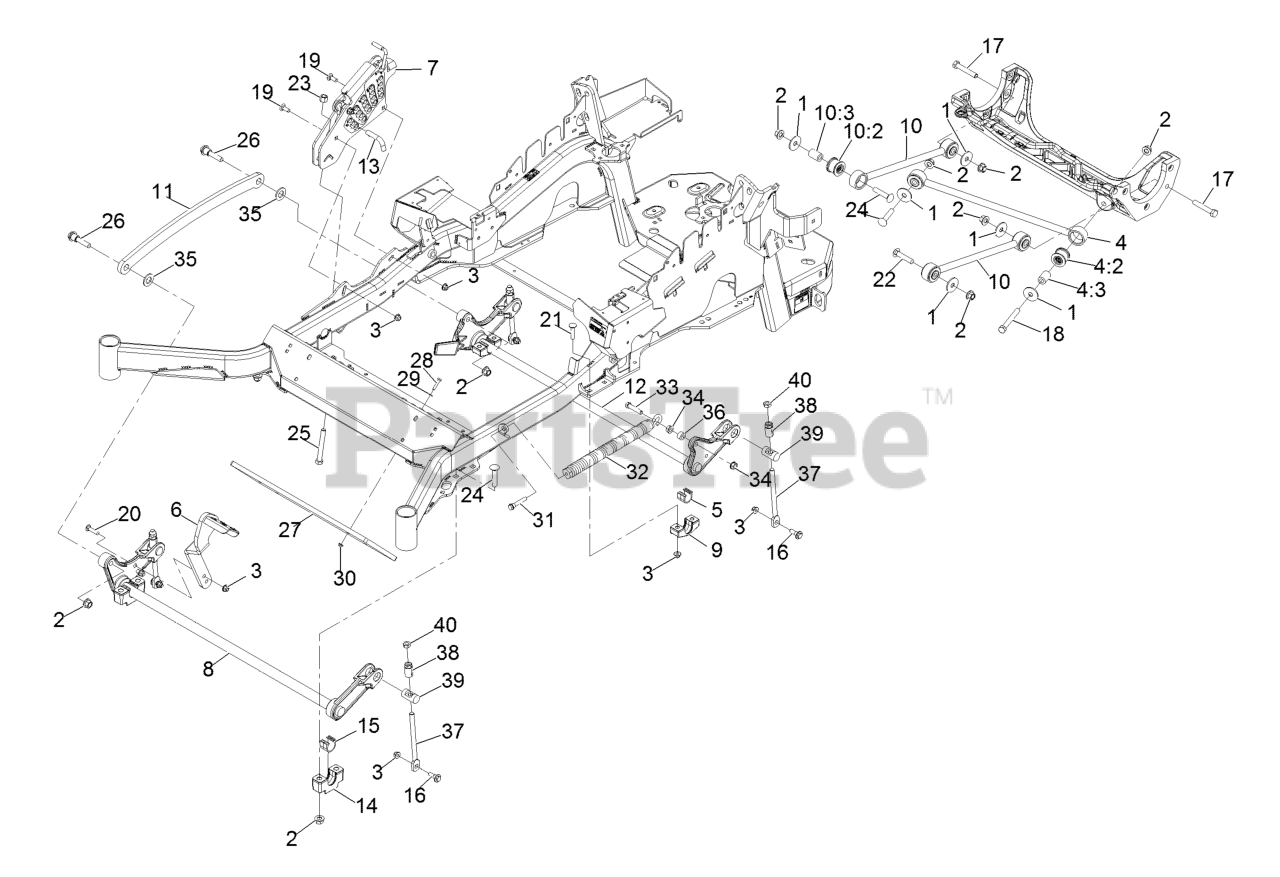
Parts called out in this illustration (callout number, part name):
1	WASHER-THRUST
2	Nut-Lock 1/2-13
3	NUT-HF, NI
4	PANHARD ROD ASM
4:2	BUSHING-SUSPENSION, RUBBER
5	BEARING-CROSS SHAFT, REAR
6	LEVER-FOOT
7	HOC ASM
8	DECKLIFT-FRONT
10	DECK STRUT ASM
10:2	BUSHING-SUSPENSION, RUBBER
11	LINK-LIFT, DECK
12	LIFT-DECK, REAR
13	PIN-HOC
14	SUPPORT-CROSS SHAFT, BEARING
15	BEARING-CROSS SHAFT, FRON
16	SCREW-SHOULDER, HHF
17	SCREW-HH
18	SCREW-HH
19	BOLT-CARR
20	SCREW-CARR
21	SCREW-CARR
22	SCREW-CARR
23	NUT-LOCK, NI
24	Bolt-Carriage 1/2-13 X 2 1/2 Spl Neck
25	BOLT-TAP
26	SCREW-HHF, SHOULDER
27	WEIGHT,TOE BOARD
28	SCREW-HH
29	WASHER-FLAT
31	BOLT-SHOULDER
32	SPRING-EXTENSION
33	SCREW-HH
35	WASHER-FLAT
37	LINK-ADJUSTER, DECK LIFT
38	ADJUSTER-LIFT, DECK
39	TRUNNION
40	NUT-JAM
